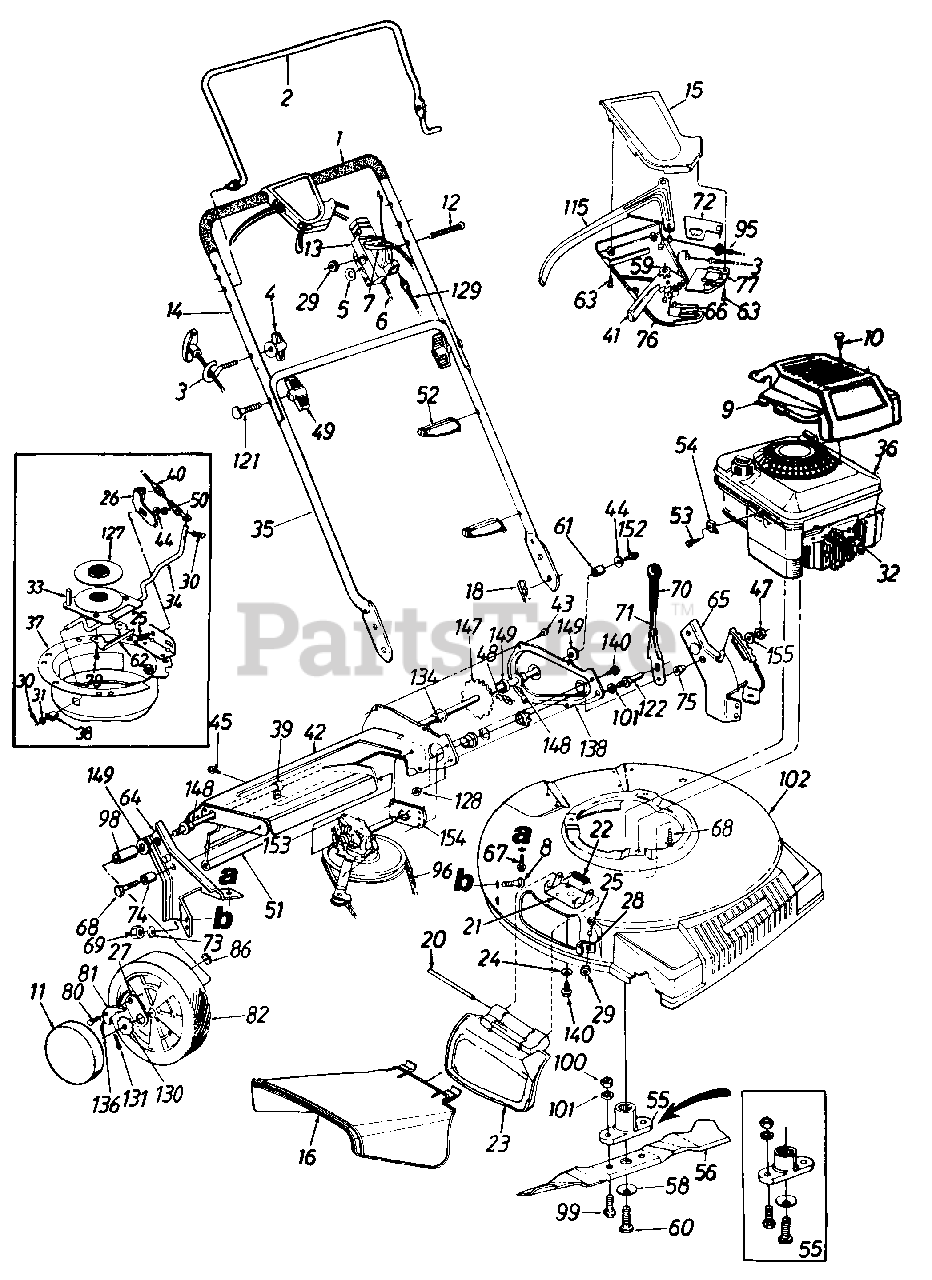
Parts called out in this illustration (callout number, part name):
1	Grip (2 Req'd.)
2	Control Handle
3	Rope Guide
4	Wing Nut 1/4-20 Thd.
5	Curved Spring Wash. .66" I.D.
6	Throttle Wire-55" Lg.
7	Throttle Lever
8	Carriage Bolt 5/16-18 x .62" Lg.
9	Engine Shroud
10	Hi-Lo Screw #10 x 1.25" Lg.
11	Hub Cap
12	Oval C-Sunk Mach. Scr.
13	Throttle Body
15	Upper Control Housing
16	Side Chute Deflector
18	Internal Cotter Pin 5/16" Dia.
20	Hinge Pin
22	Torsion Spring
23	Mulch Plug Ass'y. Comp.
24	Bell-Wash. .265" I.D. x .75" O.D.
25	Carriage Bolt 1/4-20 x .5" Lg.
30	Cotter Pin 3/32" Dia. x .75"
31	Fl-Wash. .328" I.D. x .68"
32	Spark Plug Insulator
33	Lower Pulley Half Ass'y.
34	Shift Rod
36	Engine-5 H.P.
37	Housing Ass'y.
38	Flanged Bushing
40	6 Spd. Cable
41	6 Spd. Shift Lever
44	Bell-Wash. 1/4" I.D.
45	Truss Mach. B-Tap Scr. #10 x .5"
47	Hex Patch L-Nut 3/8-24 Thd.
48	#48 Chain .500" Pitch x 38 Links
49	Hand Knob
50	Hex L-Nut 1/4-20 Thd.
51	Rear Flap 3.75" x 17.5" Lg.
52	Cable Tie
53	Hex Wash. Hd. Scr. #10-32 x .62" Lg.
54	Casing Clamp
55	Blade Adapter Kit
56	21" Mulching Blade
58	Bell-Wash. .47" I.D. x 1.14" O.D.
59	Gear Insert
60	Hex Bolt 7/16-20 x 2.5"
61	Spacer.513" I.D.
67	Hex B-Tap Scr. 5/16-18
68	Hex TT-Tap Scr. 3/8-16
69	Hex Nut 5/16-18 Thd.
71	Height Adj. Lever
72	6 Spd. Rack Cable Brkt.
73	Bell-Wash. 5/16" I.D.
74	Spacer.383" I.D.
75	Shld. Spacer .5" Dia.
76	Lower Control Housing
77	Cable Mounting Cap
79	Hex Wash. Hd. Tap Scr. 1/4-20 x .38" Lg.
80	Shld. Scr. .342" Dia. x .268
81	Pawl
82	Wheel Ass'y. Comp.
86	Weld Top L-Nut 1/4-20 Thd.
95	S.P. Cable
96	"V"-Belt
98	Sleeve .526" I.D.
99	Hex Bolt 3/8-24 x 1.0" Lg.
100	Hex Nut 3/8-24 Thd.
101	L-Wash. 3/8" I.D.
121	Curved Hd. Bolt 5/16-18 x 2" Lg.
122	Shld. Pin 1.43" Lg.
127	Pulley Half-Serrated
128	Hex Jam Nut 3/8-24 Thd.
129	Control Cable-39"
130	Ratchet Wheel 1.62" O.D.
131	Cotter Pin 1/8" Dia. x 1"
134	Hex Flange Bearing
136	Spring-Nylon
147	Rear Shaft Ass'y. 21.44" Lg.
148	Hex Flange Brg. .506" I.D.
149	Fl-Wash. .531" I.D. x .930"
152	Hex Bolt 1/4-20 x .62" Lg. (Grade 5)
153	Transmission Comp. (See Breakdown)
155	Fl-Wash. .385" I.D. x .87" O.D.
